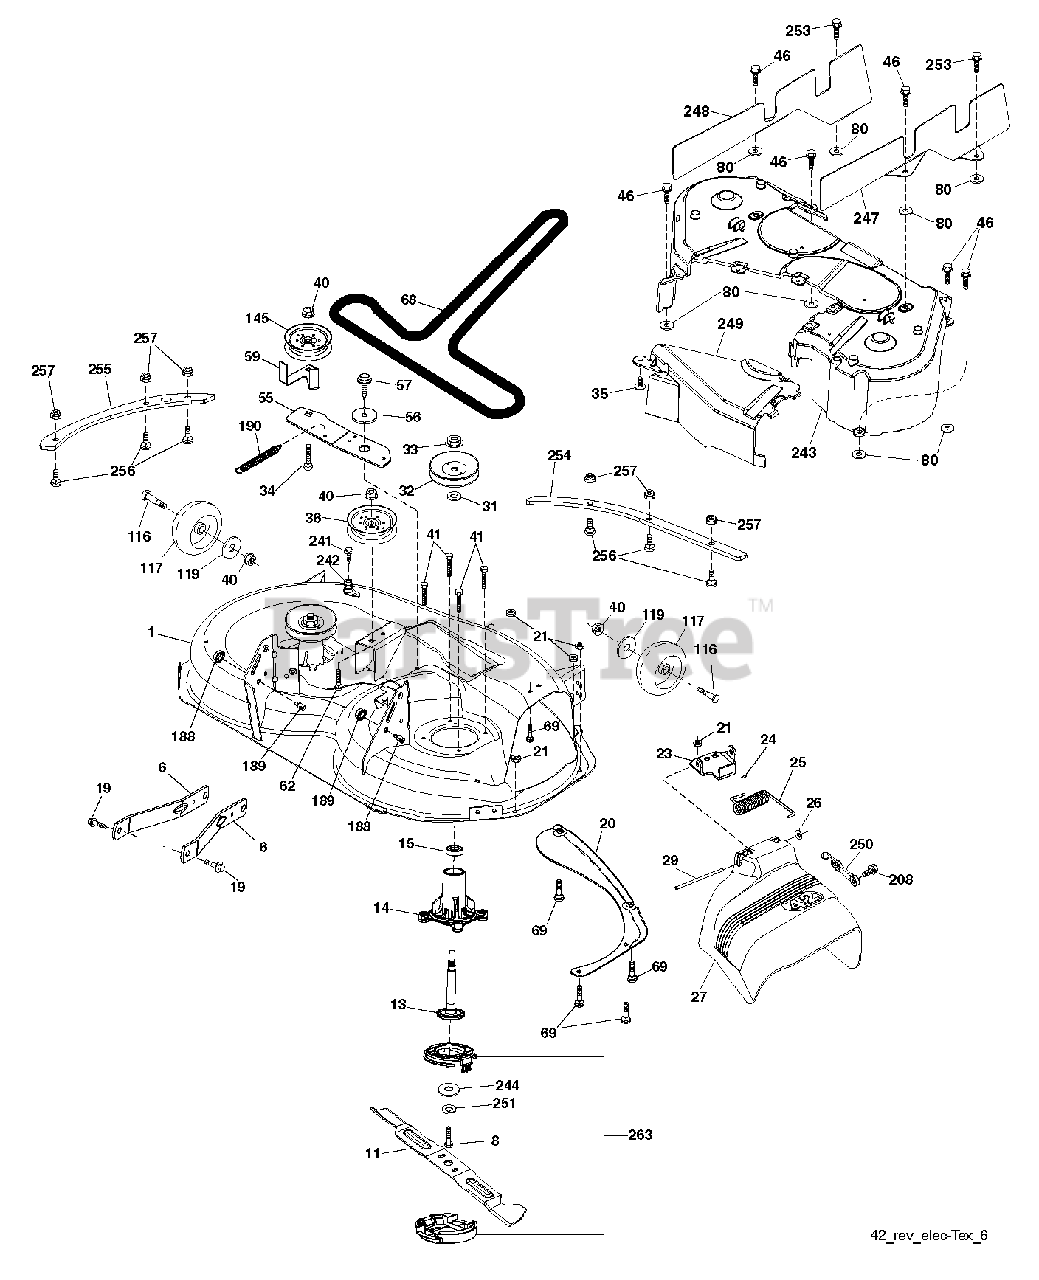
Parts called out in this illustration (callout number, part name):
1	DECK SVC 42"B 103 419175X498
6	ARM.SUSPENSION.MOWER.R
8	SCREW 7/16 X 20 X 1" HEX HEAD
11	BLADE.REVOLUTION.42"3IN1.PT43
13	SHAFT ASM.REV.TALL.N/GREASEBL
14	HOUSING.MANDREL.REV.TALL.N/GRS
19	BOLT.SHOULDER
20	BAFFLE.VORTEX
21	LOCKNUT
23	BRKT.DEFLECTOR.38"2005+
24	CAP-SLEEVE LT
25	SPRING.TORSION.DEFLECT
26	NUT PUSH M
27	DEFLECTOR ASM.42"TEX.FRENCH
29	ROD.HINGE
31	WASHER.SPACER.MANDREL
32	PULLEY/MANDREL
33	NUT.FLANGE.LOCK.TOP
34	BOLT.3/8-16X1.50
35	FASTENER.XMAS.TREE
36	PULLEY.IDLER.2006
40	NUT LOCK FLG 3/8-16 UNC
41	BOLT.HEX.WASHR.HED.313-18X1.19
46	SCREW.1/4-20X5/8
55	IDLER.ARM.42"
56	SPACER.RETAINER
57	SCREW 3/8-16X1
59	GUARD, BELT
68	BELT V SECONDARY
69	BOLT
80	PALNUT 1/4
116	BOLT M
117	WHEEL.GAGE.HALF.SPOKED
119	WASHER
145	PULLEY.IDLER.48"PRIMARY
188	STUD.FASTNER.W/ANTI-ROTATE
189	NUT LOCK HEX FLANGE 5/16-18
190	SPRING.MOWER.DRIVE.ELECTRIC
208	SCREW 3/8-16X1/2
241	SCREW.TT.#10-32X.5.3/8.FLANGE
242	PORT.WASHOUT
243	COVER DECK
244	Flat Washer, 7/16"
247	SHIELD RIGHT
248	SHIELD LEFT
249	COVER CABLE CLUTCH
250	ELASTIC STRAP KIT
251	LOCKWASHER
253	SCREW
254	PLATES.RENFRC.42DECK.PT431FRNT
255	PLATES.RENFRCE.42DECK.X431SIDE
256	RHSNB, 1/4-20 X 1, GR5
257	NUT T
263	CAP.REVOLUTION BUMPER
